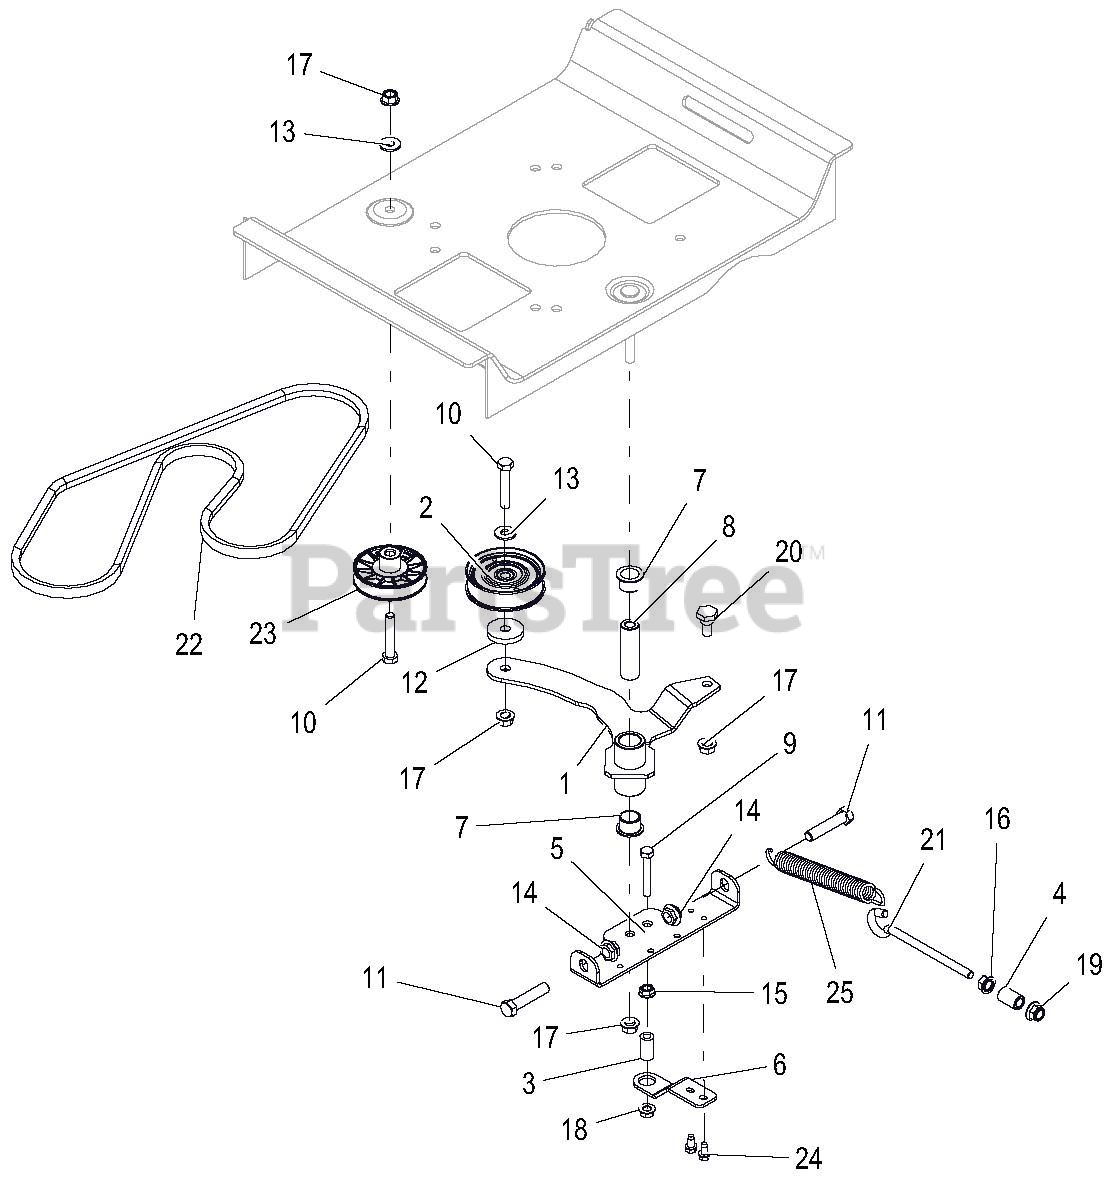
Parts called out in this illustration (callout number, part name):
1	WLDMT, IDLER GROUND DRIVE
2	IDLER, FLAT - 3.05" X .75"
3	SPCR, RUBBER 5/16 ID X 1.0 LG
4	SPCR, .375X.625X.970
5	BRKT, IDLER ATTACHMENT
6	BRKT, CLUTCH STOP
7	BSHG, FLANGE 0.75 X 0.875 X 0.625 X 0.125
8	BSHG, SLV .380x.750x2.53
9	BLT-HEX .31-18X2.00 GR5 YWZC
10	BLT-HEX .38-16X2.00 GR5 YWZC
11	BLT-HEX .44-14X2.00 GR5 YWZC
12	SPACER, .39 X 1350 X .380
13	WSHR-FL-STL.38X.875X.083 YWZC
14	NUT-LK-NYL-FLG .44-14 YWZC
15	@NUT-SPNLK-FLG .312-18 YWZC
16	@NUT-SPNLK-FLG .375-16 YWZC
17	NUT, LK-TOP-FLG .38-16 YWZC
18	NUT, LK-TOP-FLG .312-18 YWZC
19	NUT-LK-NYL-FLG .38-16 YWZC
20	BLT, SHLDR EP .38-16X.30 HEX YZ
21	BOLT, EYE .38-16X6.00 .62 DIA
22	V-Belt, A-RAW EDGE
23	IDLER, V 3.00" COMPOSITE
24	SCR-TAP .25-20X.50 HWH TR YWZ
25	SPRG, EXTENSION .120X.845X6.55 WLD
